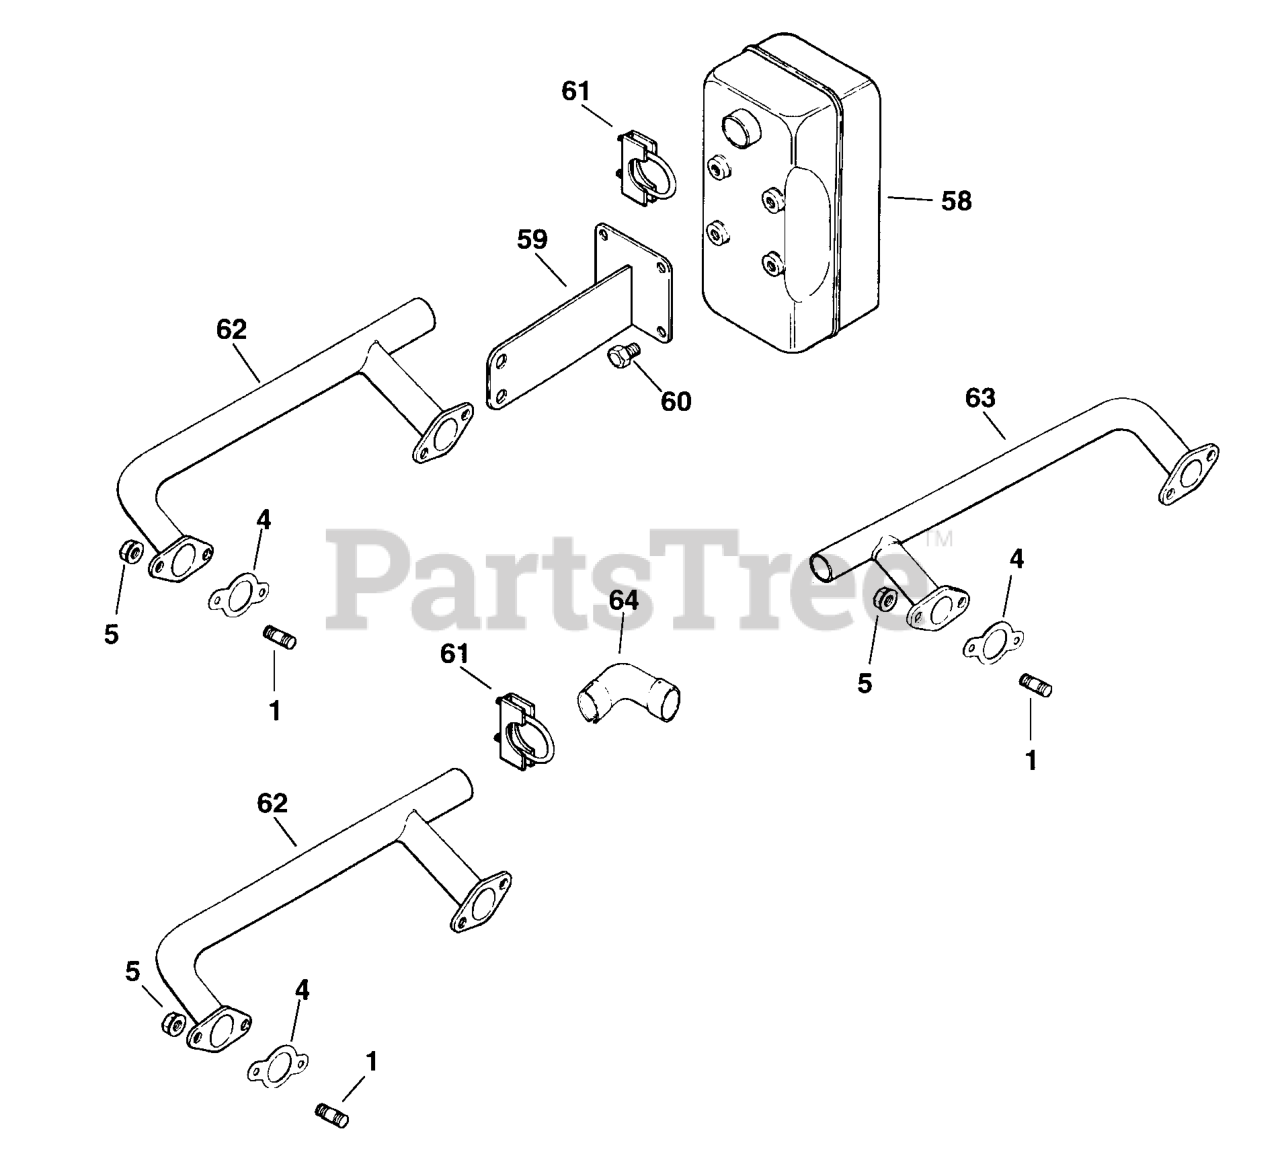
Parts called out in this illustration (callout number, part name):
1	STUD - USE M-829033
5	NUT - USE M-841080
58	MUFFLER USE 24 068 126-S
59	BRACKET, MUFFLER
60	SCREW, WSH HD TAP 1/4-20X1" USE 25 086 108-S
62	MANIFOLD, EXHAUST - DISCONTINUED
